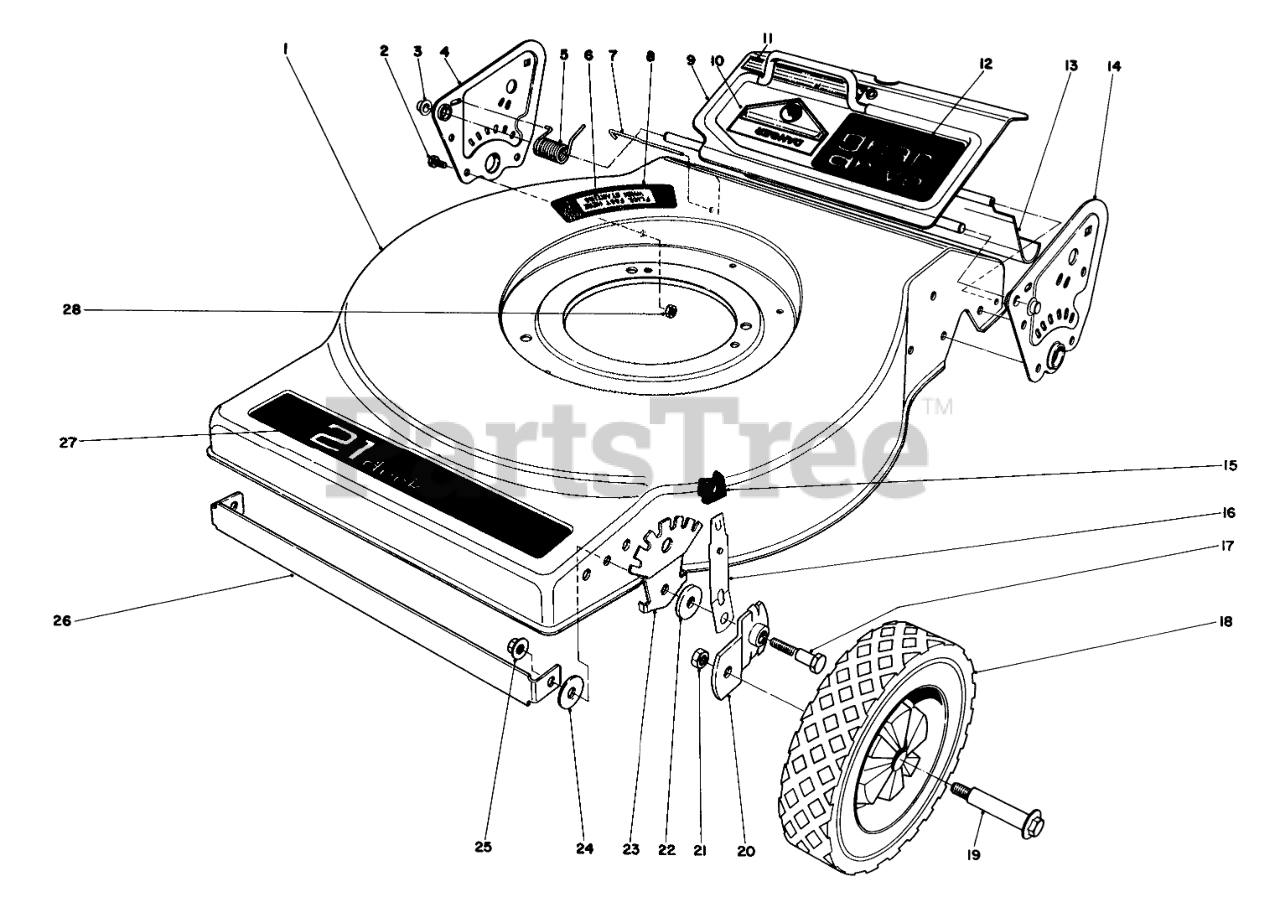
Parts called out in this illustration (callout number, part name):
1	Housing
2	SCREW-HH
3	RETAINER-PUSH ON
4	Side Plate R.H
5	TORSION SPRING
6	Decal Step Pad
7	SHIELD ROD
8	PAD STEP
9	Rear Door
10	DECAL-DANGER
11	Decal-Door
12	Decal-Door
13	SAF SHIELD REAR
14	Side Plate L.H.
15	KNOB-ARM
16	SPRING ARM ASM
17	PIVOT SCREW
18	Wheel & Tire Assembly
19	BOLT-WHEEL
20	PIVOT ARM ASM A
21	Nut
22	PIVOT WASHER
23	Quadrant
24	WASHER
26	DECK SUPPORT
27	Decal-Deck
